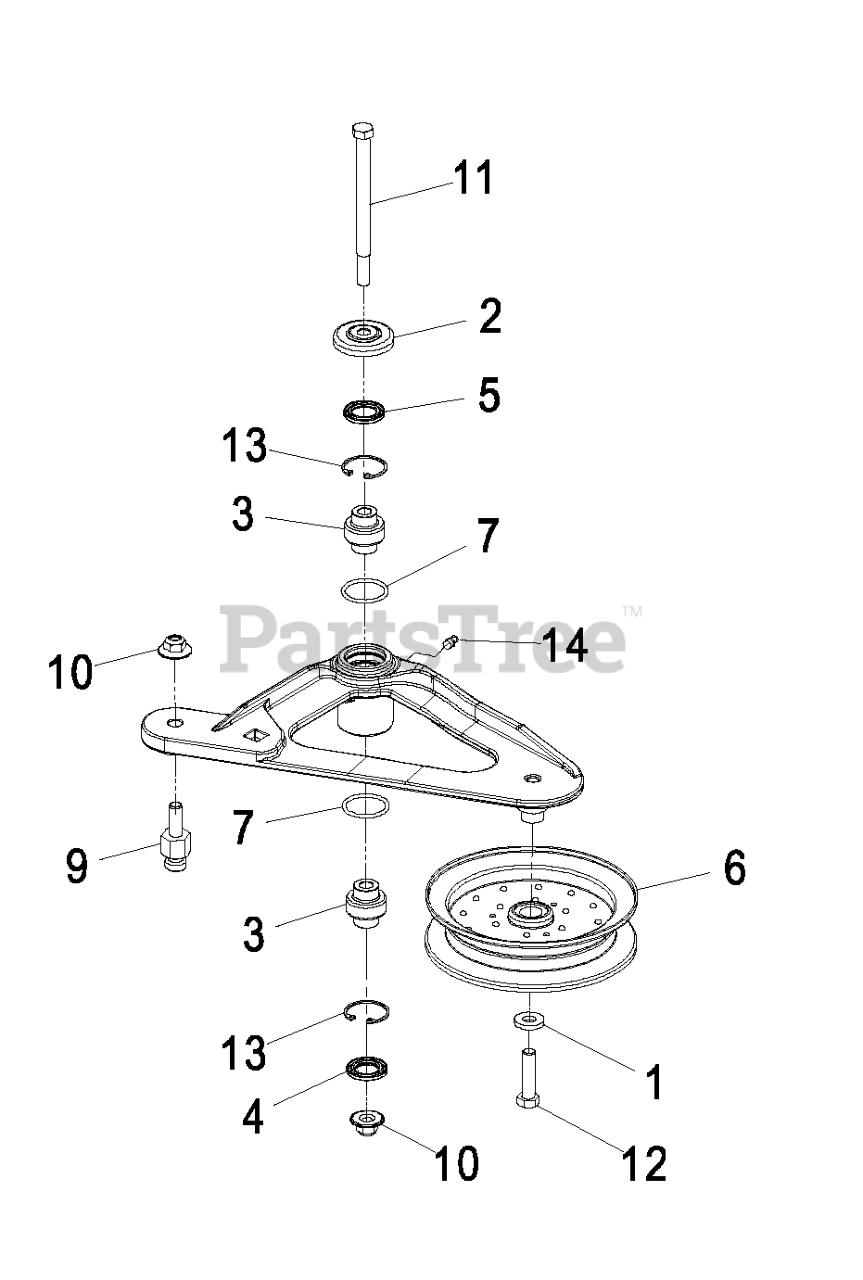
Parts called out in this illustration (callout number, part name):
2	GUARD-TOP
3	BEARING-SPHERICAL
4	SEAL-LIP, DOUBLE
5	SEAL-LIP, SINGLE
10	Nut-Nyloc 3/8-16 Flg
11	SCREW-SHOULDER, HH
12	SCREW-HH
13	RING-SNAP
14	FITTING-GREASE
